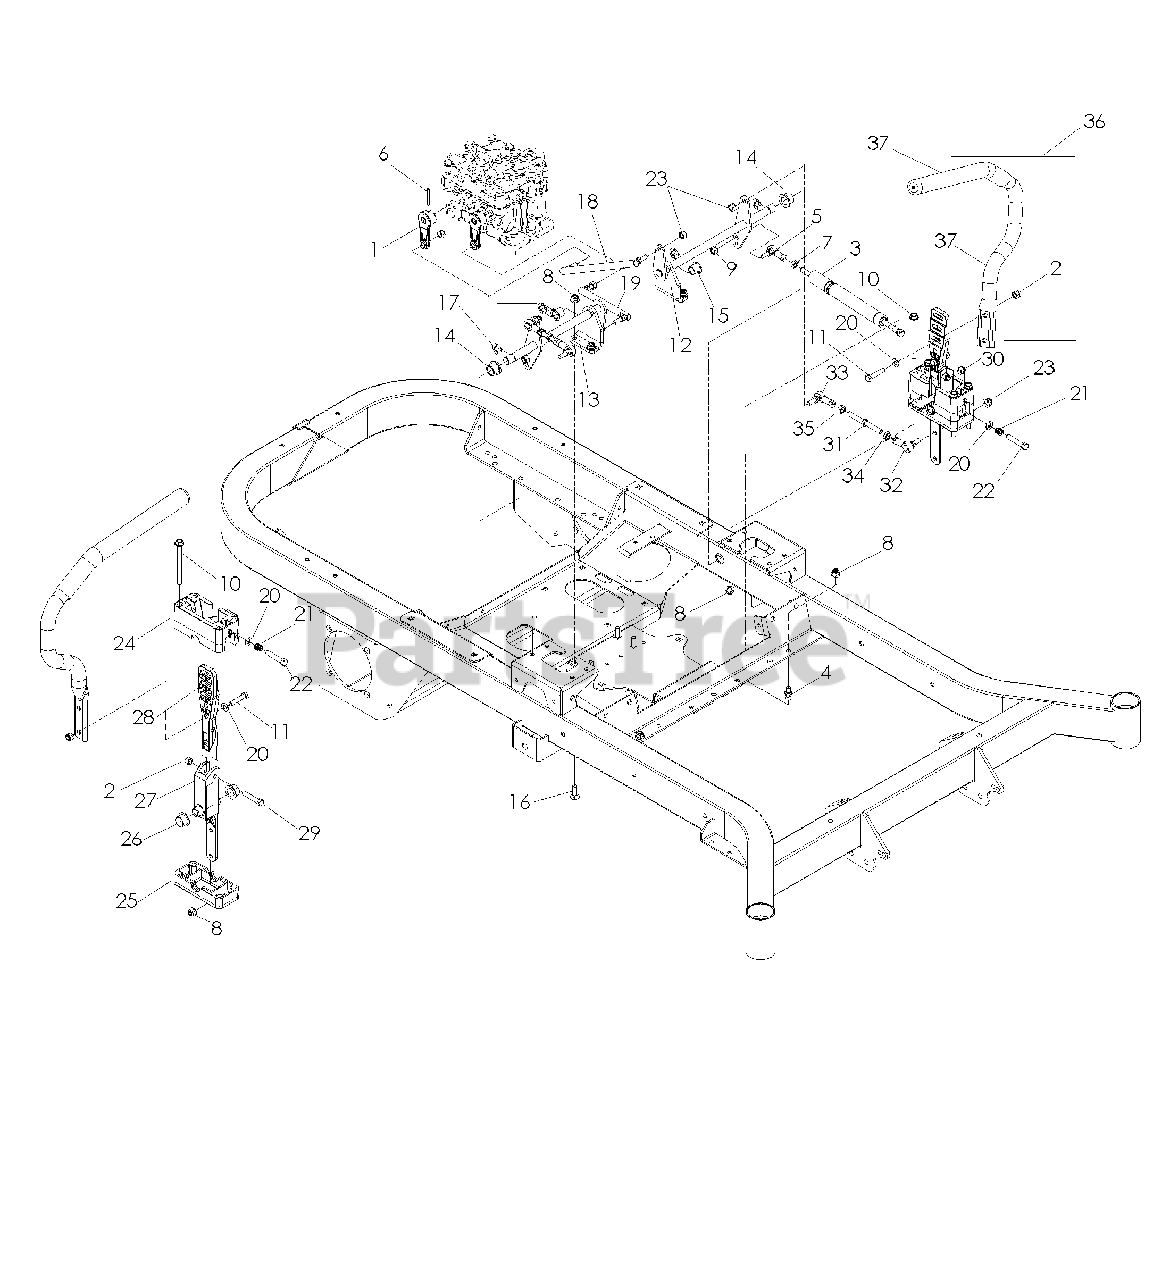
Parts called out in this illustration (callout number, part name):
1	ARM PUMP
2	NUT 5/16 NYLOC
3	DAMPENER W/SPRING
4	STUD.BALL.10MM
5	ROD END
6	PIN, SPIRAL, 5/32 X 1 1/2
7	NUT M8 X 1.25 STD HEX
8	5/16-18 NYLOC FLANGE NUT
9	NUT M8 NYLOC
10	HHFS 5/16-18 X 3 3/4
11	CAPSCREW 5/16 X 1/1/2 HEX HEAD
12	CONTROL WLDMT, LT
13	CONTROL WLDMT, RT
14	BUSHING, FLANGED, 5/8
15	BUSHING, CLIP, 5/8
16	RHSNB 5/16C X 1
17	E-RING 5/8
18	LINK, MOTION, LT
19	LINK, MOTION, RT
20	FLAT WASHER 5/16 SAE
22	HCS 5/16-18X1-3/4 TPBLT
23	NUT 5/16-24 CNTRLK
24	BLOCK, UPPER
25	BLOCK, LOWER
26	BEARING, FLANGE
27	PIVOT SECTION, DR CNTRL
28	MOUNT, DR CNTRL HANDLE
29	HCS 5/16C X 1 3/4
30	NUT 5/16C HEX
31	JACK SCREW
32	SPHERICAL ROD END, LH
33	SPHERICAL ROD END, RH
34	NUT 5/16F LEFTHAND
35	NUT 5/16F
36	LEVER.DRIVE.W/GRIP
37	GRIP - DRIVE LEVER
